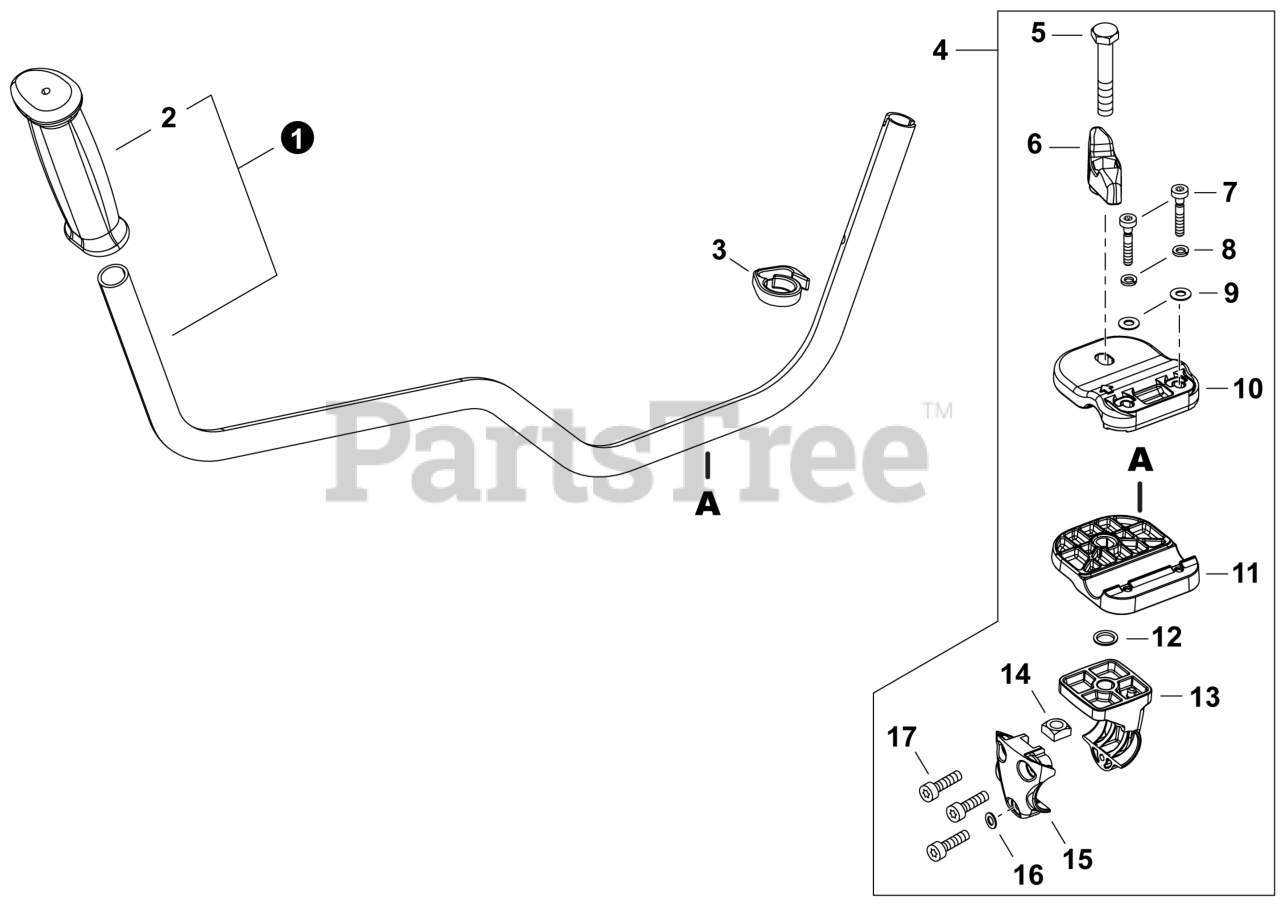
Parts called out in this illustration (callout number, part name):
1	HANDLEBAR ASSY
2	GRIP, HANDLE
3	CLIP, CABLE
4	BRACKET KIT, HANDLEBAR
5	BOLT M8x1.25
6	KNOB, FASTENER
7	BOLT 5x30
8	WASHER, SPRING 5
10	BRACKET, HANDLE - UPPER
11	BRACKET, HANDLE - LOWER
12	O-RING 7
13	BRACKET, MOUNTING - RIGHT
14	NUT 8x1.25
15	BRACKET, MOUNTING - LEFT
16	WASHER, FLAT 5.5x10x0.8
17	BOLT, TORX 5x25
